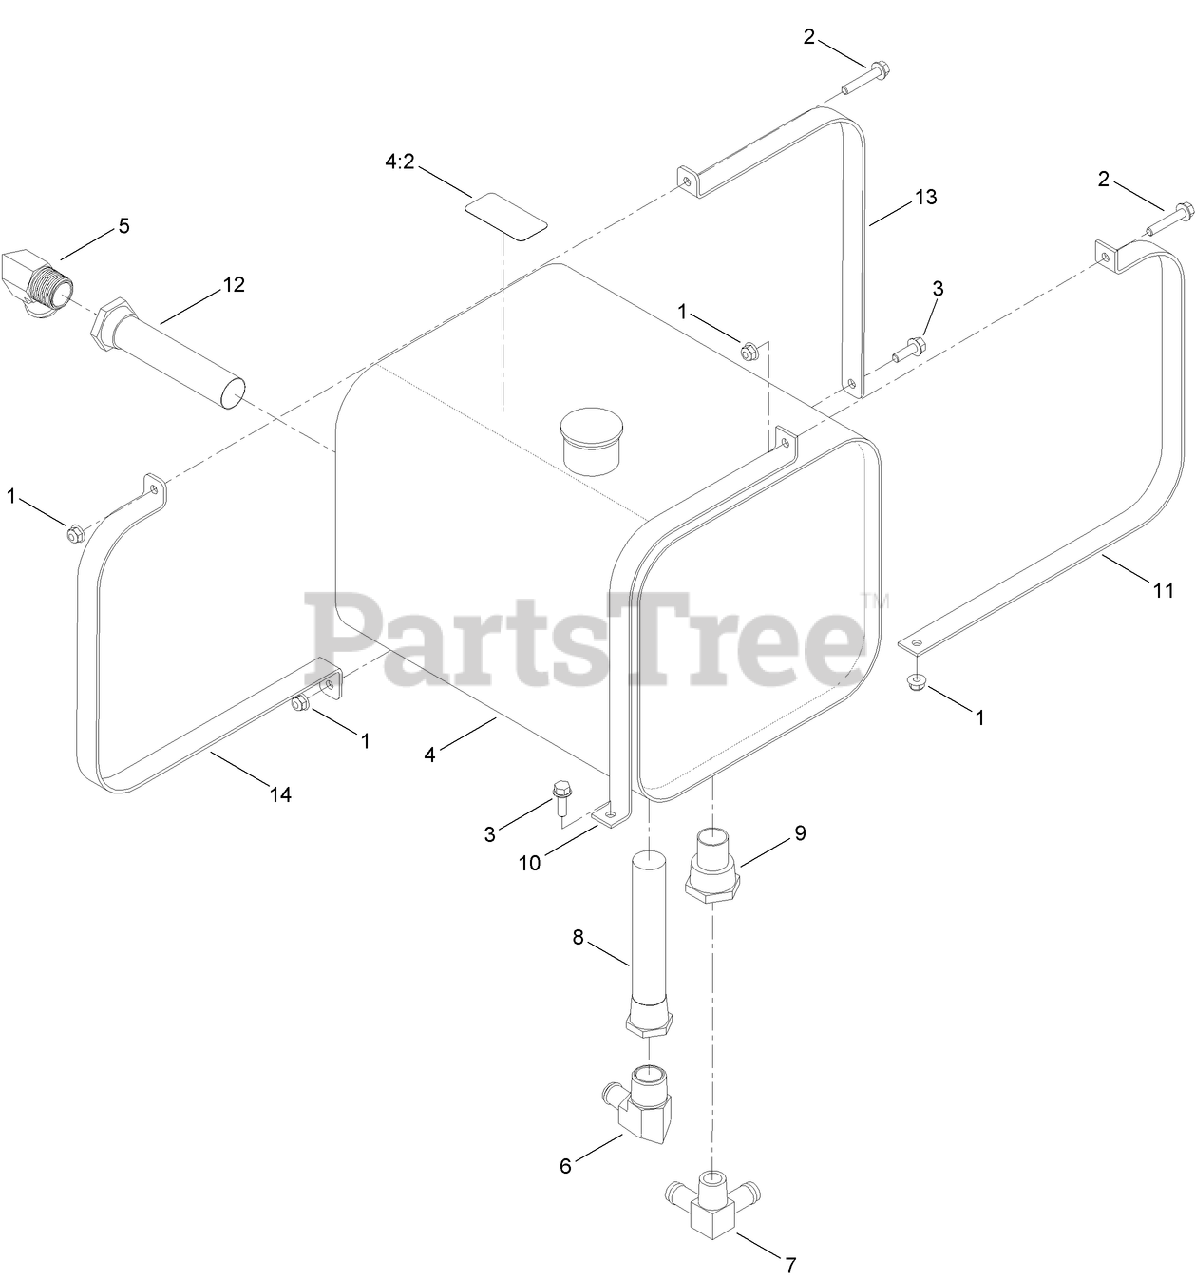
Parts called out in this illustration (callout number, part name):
1	NUT-HF, NI
2	SCREW-HWH
3	SCREW-HHF
4	HYD TANK ASM
4:2	DECAL-HYD FLUID
5	FITTING-ELBOW, 90
6	FITTING-ELBOW, 90
7	FITTING-ELBOW, LATERAL
8	FILTER ASM
9	INDUCER-PRESSURE
10	STRAP-TANK
11	STRAP-TANK
12	FILTER ASM
13	STRAP-TANK
14	STRAP-TANK
